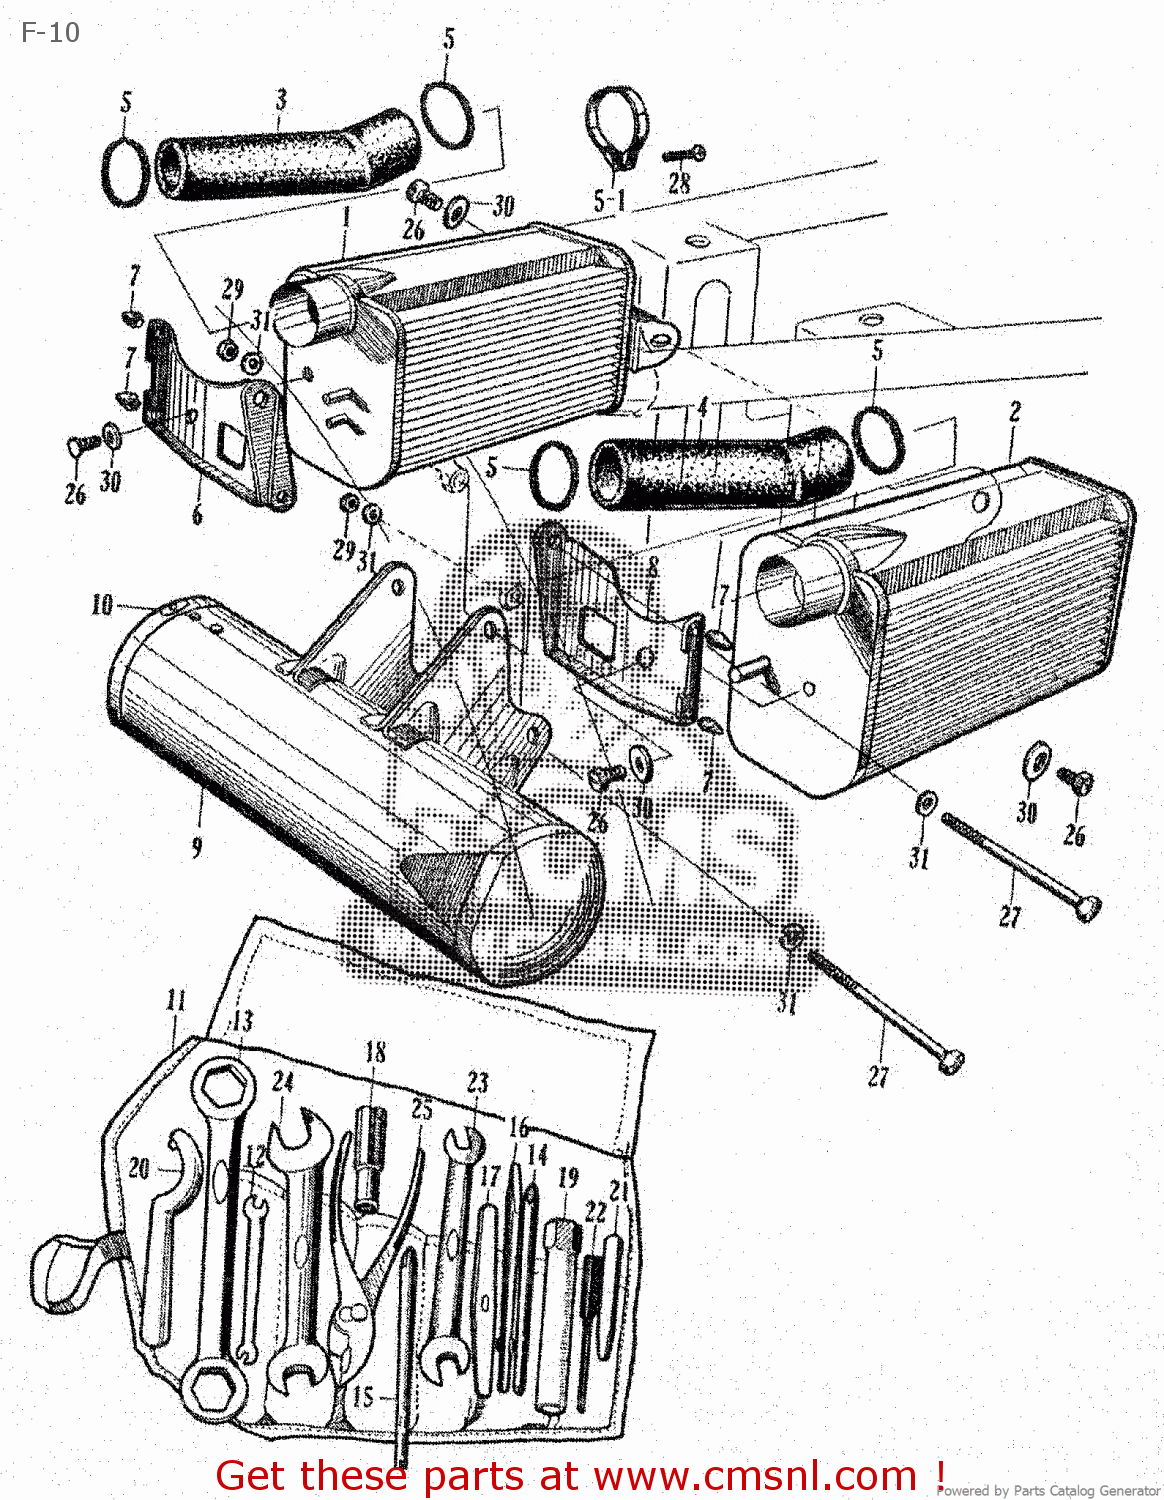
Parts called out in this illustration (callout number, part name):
1	ELEMENT CLEANER
2	ELEMENT CLEANER
3	TUBE R CLEANER
4	TUBE L CLEANER
5	BAND
6	STAY,CLEANER
7	RUBBER STAY
8	STAY L CLEANER
9	BOX TOOL
10	TOOL SET
11	BAG TOOL
12	WRENCH TAPPET
13	WRENCH AXLE
14	DRIVER
15	DRIVER
16	SCREW DRIVER,3
17	LEVER
18	GRIP,SCREW DRIVER
19	WRENCH PLUG
20	SPANNER 37MM
21	GAUGE TAPPET
22	FILE, POINT
23	SPANNER, 10X14
24	SPANNER, 17X19
25	PLIERS, 150
26	BOLT,HEX 6X10
27	STUD, BOLT, 6X72
28	SCREW CROSS 5X20
29	NUT,HEX 6MM
30	WASHER,PLAIN, 6MM
31	WASHER,SPRING,6MM
